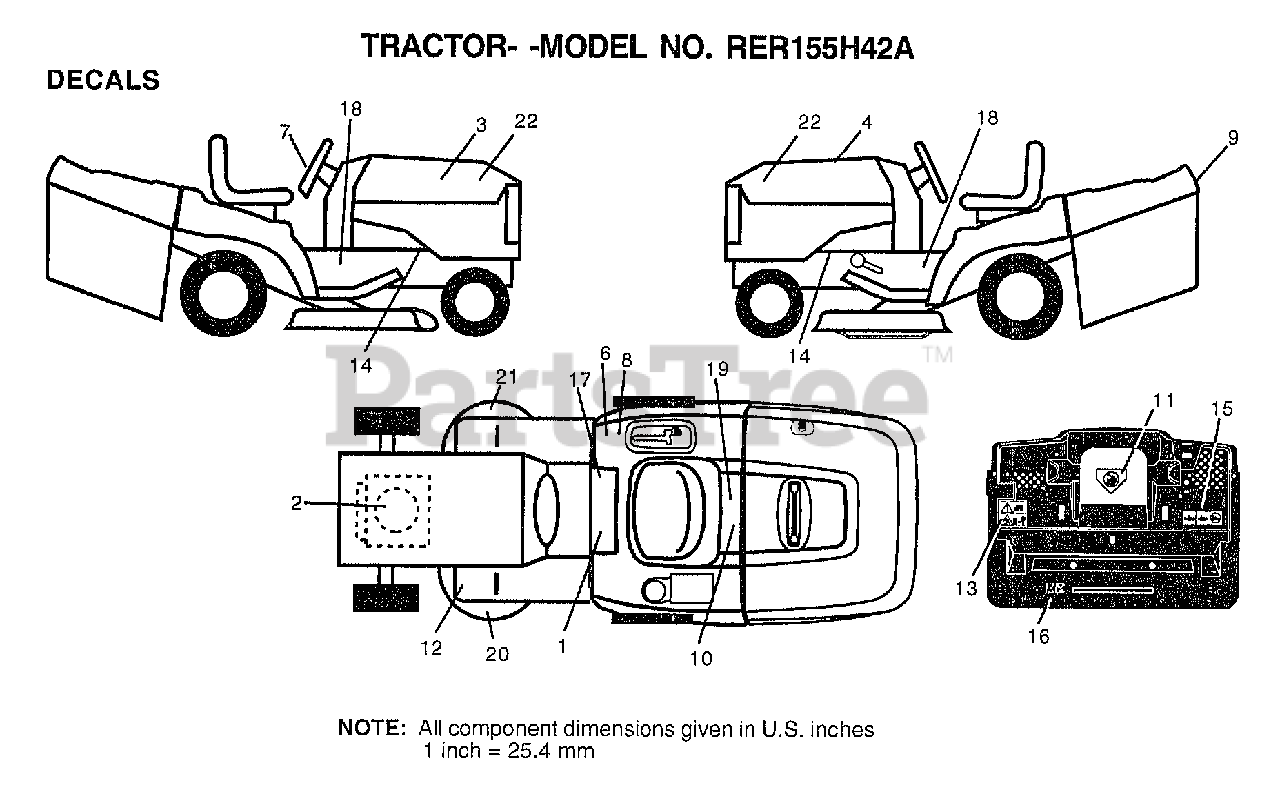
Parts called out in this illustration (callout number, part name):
1	DECAL.READ.O.MANU
3	DECAL HOOD RH
4	DECAL HOOD LH
7	"DECAL,STR WHL"
8	DECAL.EURO.ST.CE.
9	FENDER DECAL
10	DECAL.BATRY.3-3908
11	DECAL.DANGER.CUTF
12	DECAL-BRAKE/CLUTC
13	DECAL.WARNING.BACKPLATE.CRD
14	"DECAL CHASSIS,HOT"
15	DECAL, OPER BAG
16	DECAL.DRAWBAR.LDL
17	DECAL BRAK PARK
18	DECAL CHAS 42 HYD
19	DECAL.BYPASS.FENDER.CRD.LT.YT
21	DECAL.DECK.HEX.BELT
22	DECALS
